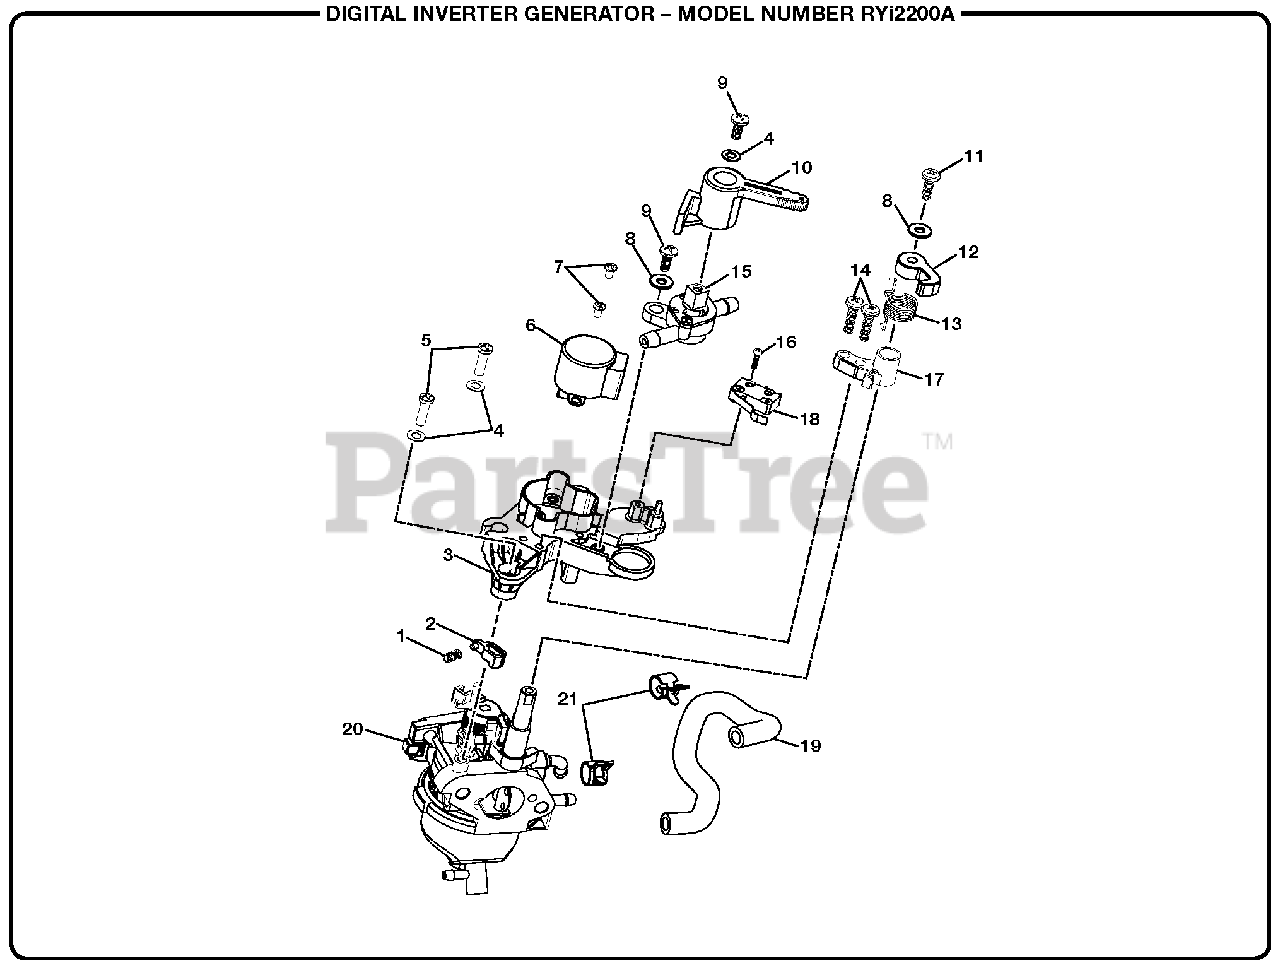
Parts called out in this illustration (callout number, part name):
1	Governor Damping Spring
2	Governor Joint
3	Governor Motor Bottom Housing
4	Washer (M4)
5	Screw (M4 x 14 mm, Pan Hd.)
7	Screw (M3 x 5 mm, Pan Hd.)
8	Washer (OD10 x ID4.2 x 1t)
9	Screw (M4 x 10 mm, Pan Hd.)
10	Control Lever
11	Screw (M4.2 x 12 mm, Pan Hd.)
12	Choke Lever Upper
14	Screw (M4.2 x 16 mm, Pan Hd.)
15	Fuel Valve
16	Screw (M2.2 x 12 mm, Pan Hd.)
17	Support Bracket
18	Engine Shut-Off Switch
19	Fuel Hose (Fuel Valve To Carb)
20	Carburetor
21	Clamp (D9.5 mm)
